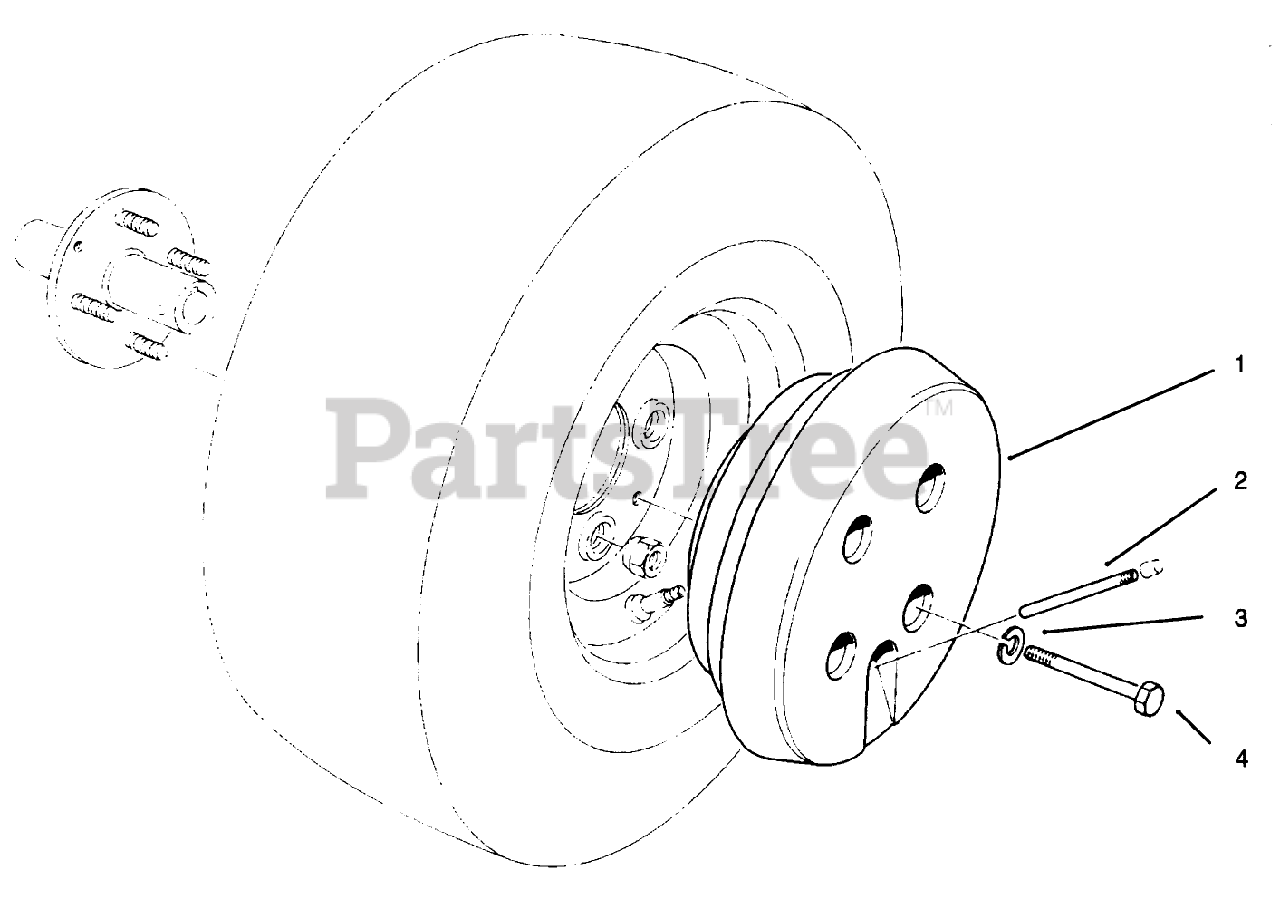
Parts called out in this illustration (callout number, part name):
1	Weight-Wheel
2	VALVE EXTENSION
3	WASHER-LOCK
4	SCREW-HH
